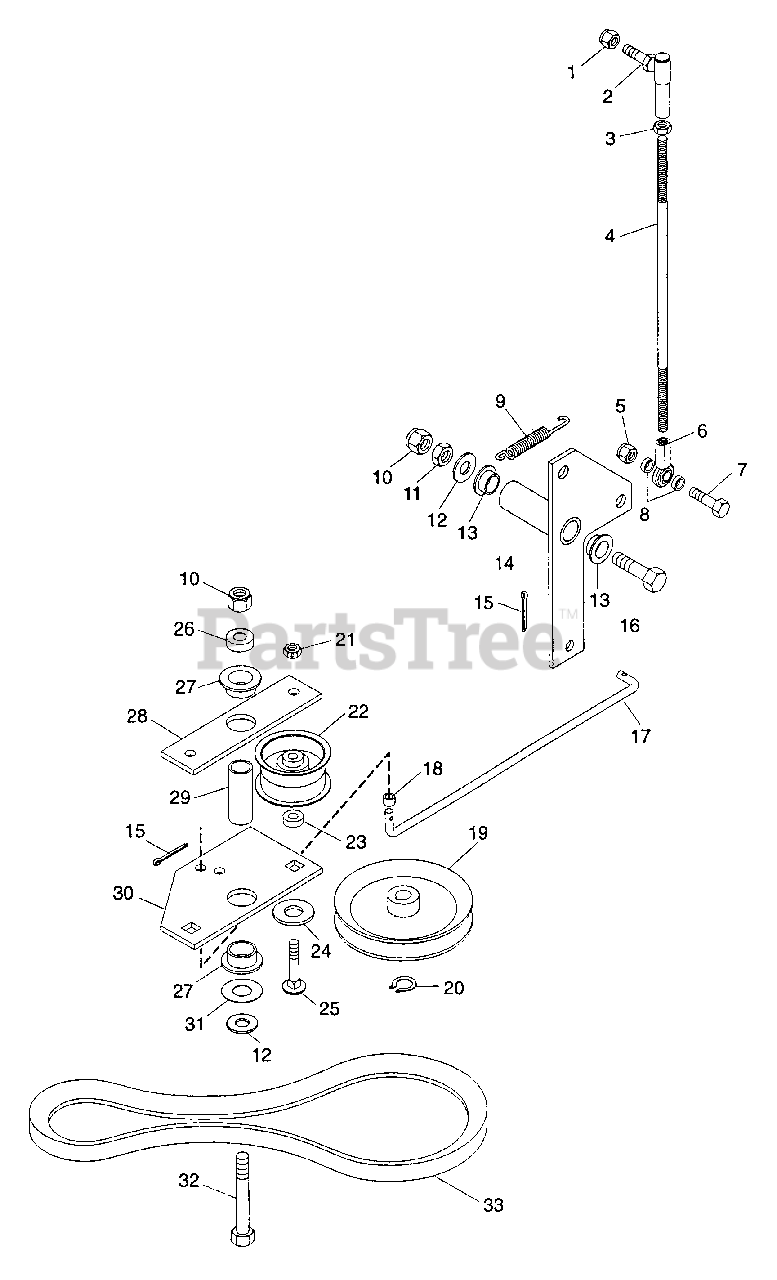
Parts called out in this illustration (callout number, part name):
1	Nut-Locking-Nylon .375-24 Grade 2
2	Joint, Steering Ball
3	Nut-Hex .375-24 Grade 2
4	Rod, Clutch Actuating
5	Nut-Locking-Nylon .375-16 Grade 2
6	Rod End, Spherical Bearing
7	Bolt-Hex .38-16 x 1.50 Grade 5
8	Bushing-Flange .383 x .50 x .165
9	Spring-Tension .095 x .500 x 5.5
10	Nut-Locking-Nylon .50-13 Grade 5
11	Nut .50-13
12	Washer-Flat-Steel .531 x 1.250 x .100
13	Bushing-Flange .515 x .750 x .745 x 1.00
14	Weldment, Clutch Arm
15	Pin-Cotter .09 x .75
16	Bolt-Hex .50-13 x 4.50
17	Rod, Traction Clutch
18	Bushing, Steel .380 x .495 x .437
19	Sheave, Transmission
20	Ring-Retaining-External .579 x .93
21	Nut-Locking-Center .625-10 Grade 2
22	Idler-Flat 2.468 x .38
23	Bushing .406 x .750 x .188
24	Washer-Flat-Steel .531 x 1.063 x .095
25	Bolt-Round Head Square Neck .38-16 x 1.75
26	Bushing, Steel .790 x 1.00 x .320
27	Bushing-Flange .762 x 1.0 x .580 x 1.48
28	Plate, Idler
29	Bushing, Steel .560 x .745 x 2.04
30	Plate, Idler
31	Bearing-Needle-Thrust .752 x 1.24 x .093
32	Bolt-Hex .50-13 x 3.00
33	V-Belt A-Section
